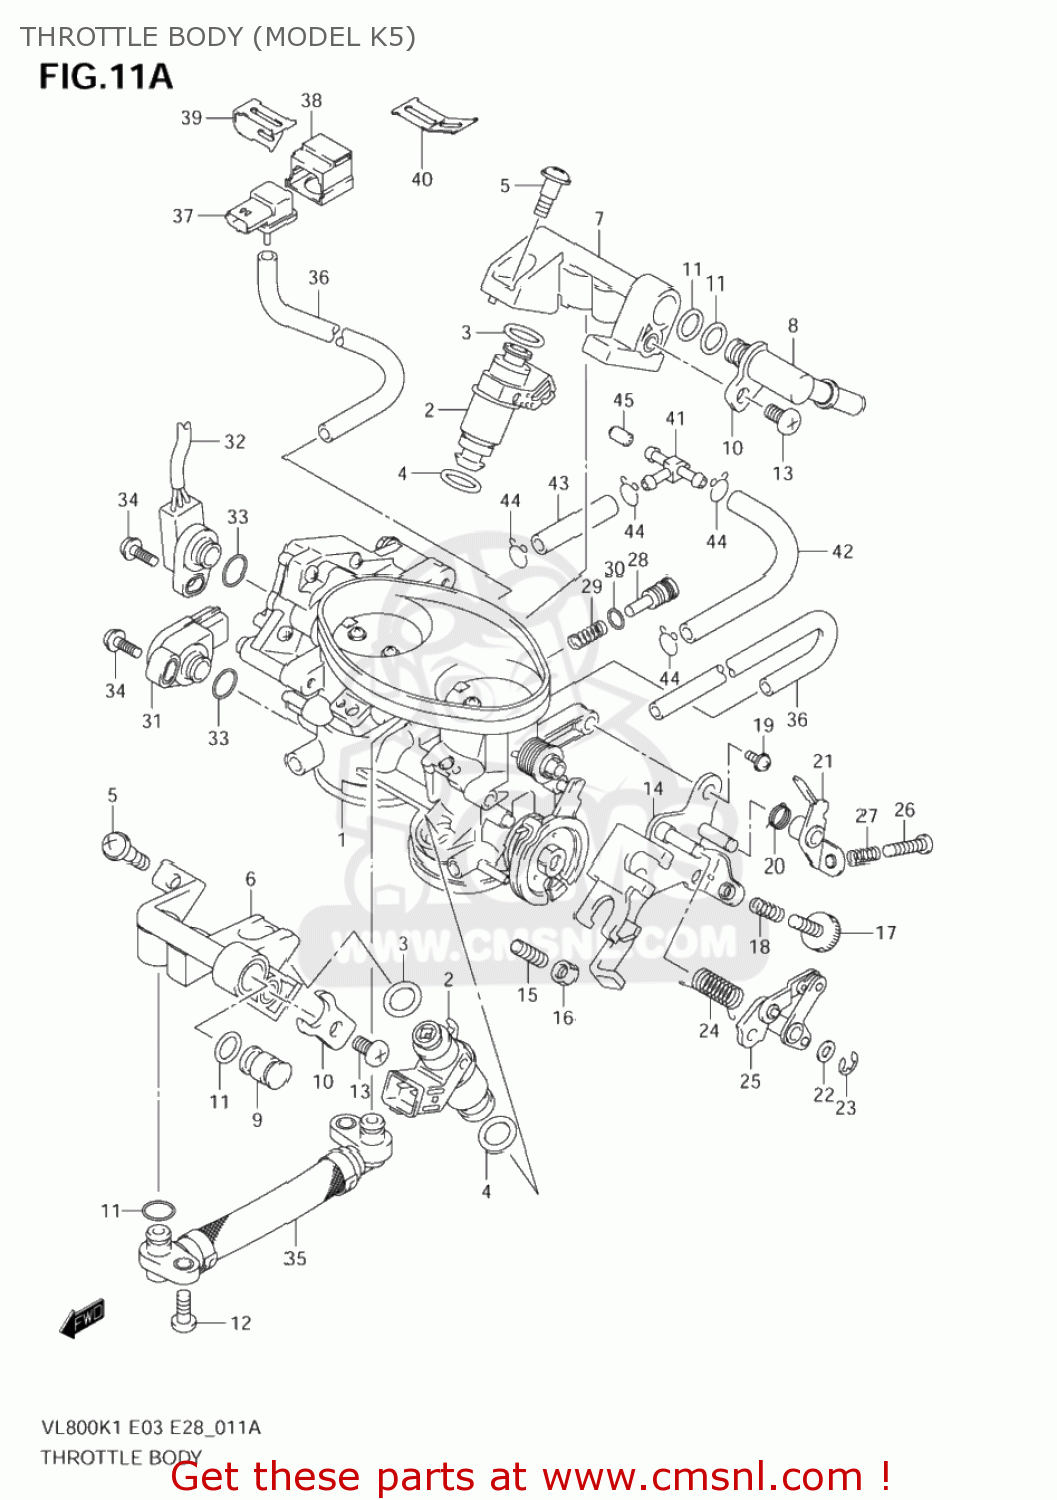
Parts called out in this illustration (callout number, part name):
1	THROTTLE BODY KIT
2	INJECTOR ASSY
3	O RING
4	O RING
5	SCREW,THROTTLE COVER
6	PIPE,FUEL
7	PIPE,FUEL
8	JOINT
9	PLUG
10	PLATE
11	O RING
12	SCREW
13	SCREW
14	PLATE,STAY
15	SCREW,STOP
16	NUT
17	SCREW,IDLE
18	SPRING
19	SCREW
20	SPRING
21	LEVER,LINK
22	WASHER
23	E CLIP
24	SPRING
25	LEVER SET,LINK
26	SCREW
27	SPRING
28	SCREW,ADJUST
29	SPRING
30	O RING
31	SENSOR ASSY,TH
32	SENSOR ASSY,TH
33	O RING
34	SCREW
35	PIPE ASSY,FUEL
36	HOSE
37	SENSOR,PRESSURE
38	HOLDER,SENSOR
39	BRACKET,BOOST SENSOR FR
40	BRACKET,BOOST SENSOR RR
41	JOINT
42	HOSE
43	HOSE
44	CLIP
45	PIPE
